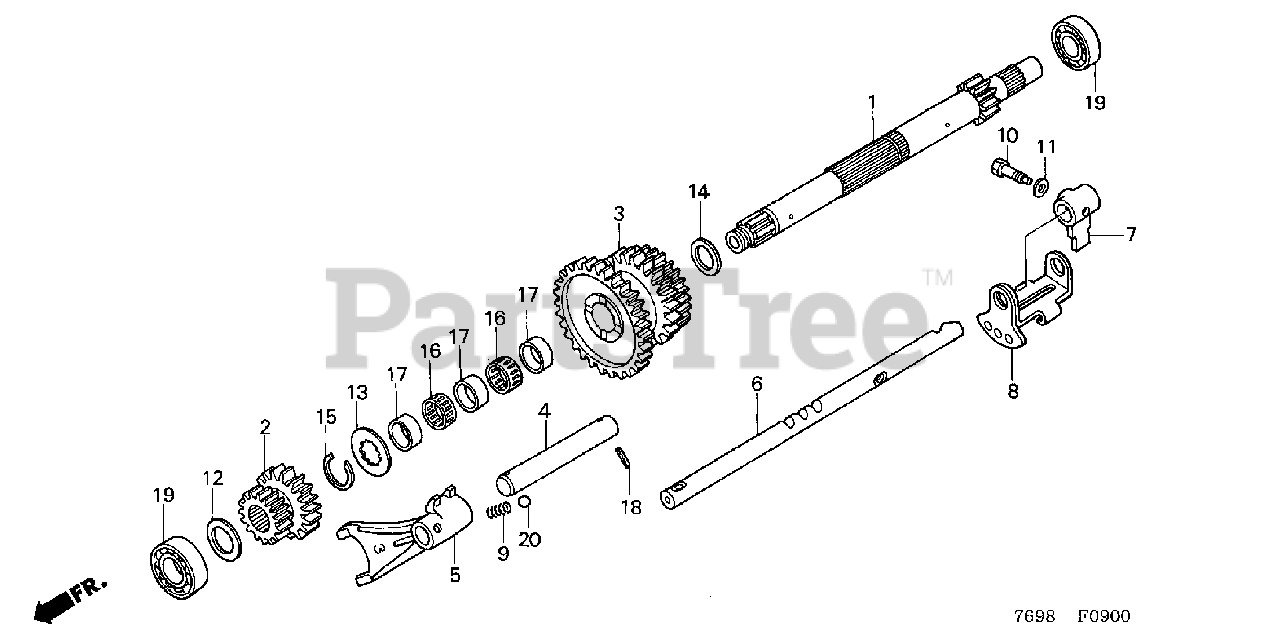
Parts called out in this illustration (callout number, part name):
2	GEAR, THIRD-FOURTH CHANGE
3	GEAR, FIRST IDLE (41T-31T-27T)
4	SHAFT, MAIN CHANGE
5	FORK, SHIFT (3-4)
6	SHAFT, SHIFT PIECE
7	PIECE, SHIFT
8	PLATE, INTERLOCK
9	SPRING A, BALL SETTING
10	BOLT, SPECIAL (8X24)
11	WASHER, CONICAL SPRING (8MM)
12	WASHER, THRUST (20X31.5)
13	WASHER, SPLINE (23MM)
14	WASHER, THRUST (24X36)
15	CIRCLIP (OUTER) (23MM)
16	BEARING, NEEDLE (24X28X13) (TOMUSON)
17	COLLAR A, FIRST IDLE GEAR
18	PIN, SPRING (3X18)
19	BEARING, RADIAL BALL (6204)
20	BALL, STEEL (#10) (5/16)
